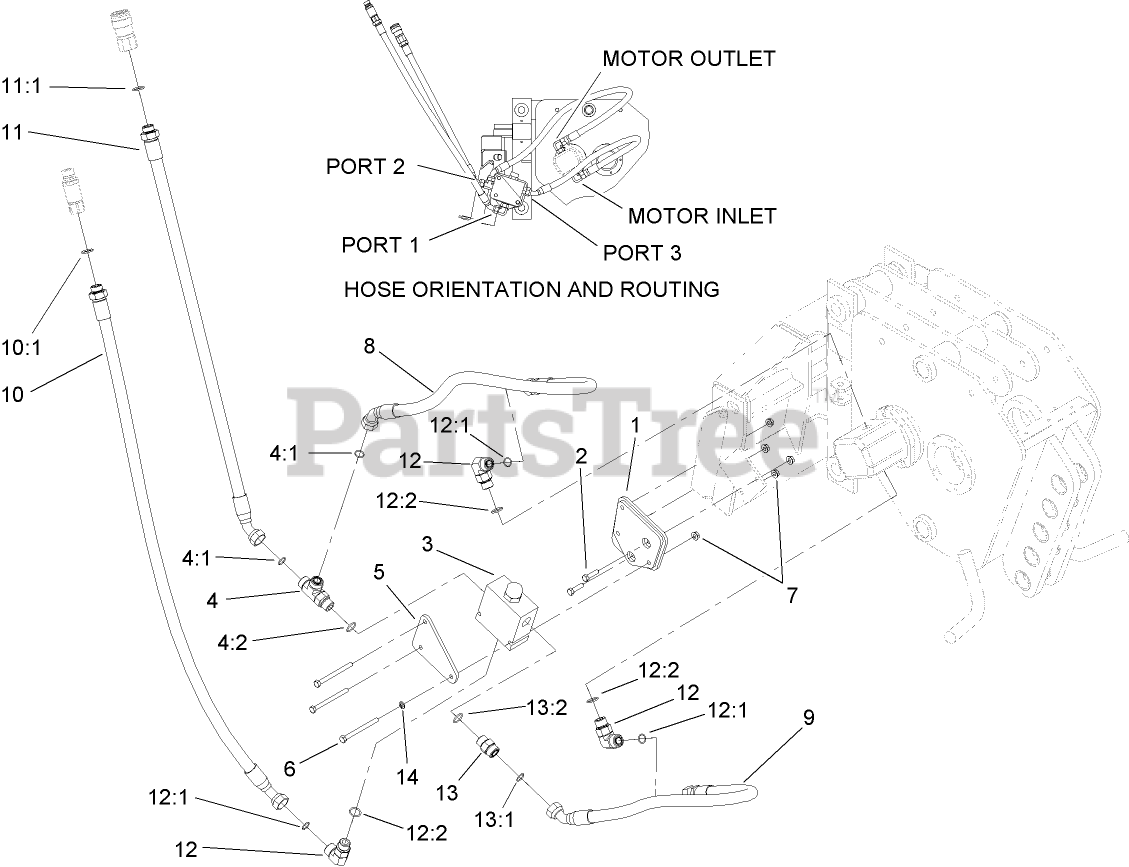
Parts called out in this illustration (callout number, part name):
1	VALVE PLATE ASM
2	SCREW-HH
3	FLOW VALVE ASM
4	FITTING-TEE
4:1	O-RING
4:2	O-RING
5	PLATE-CLAMP
6	SCREW
7	NUT-HF
8	HYD HOSE ASM
9	HYD HOSE ASM
10	HYD HOSE ASM
10:1	O-RING
11	HYD HOSE ASM
11:1	O-RING
12	FITTING-ELBOW-90
12:1	O-RING
12:2	O-RING
13	FITTING-STRAIGHT
13:1	O-RING
13:2	O-RING
14	WASHER-LOCK
